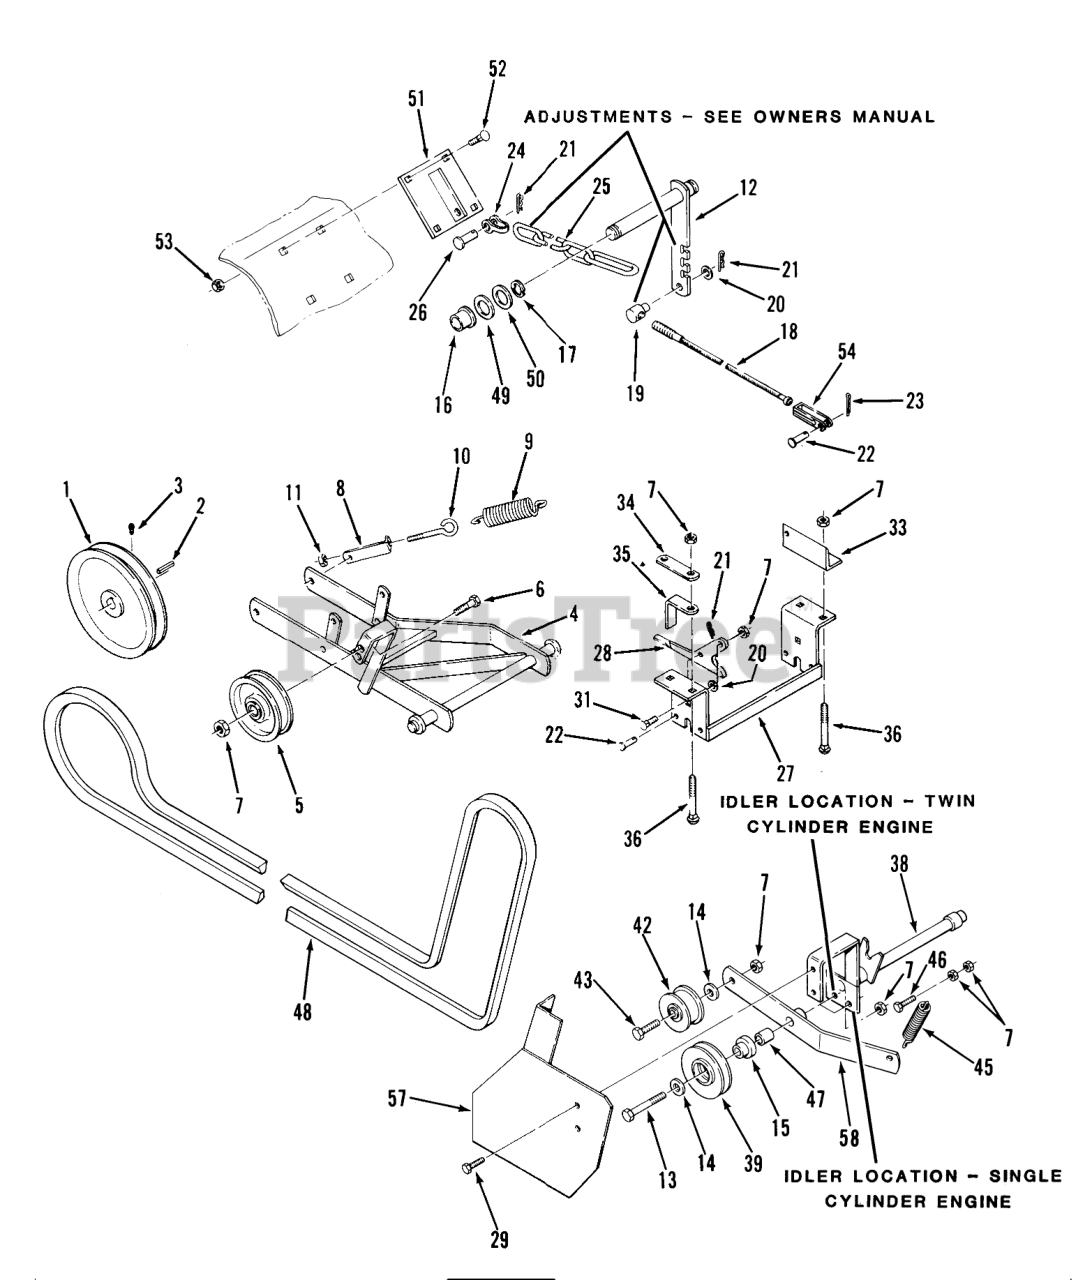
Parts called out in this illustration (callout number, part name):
1	Pulley
2	KEY-STRAIGHT
3	Set Screw
4	Hitch
5	Flat Idler
6	Bolt
7	Nut
8	Bracket-Spring
9	SPRING
10	EYEBOLT
11	NUT
12	ASSY LEVER R
13	Bolt
14	Washer
15	Spacer
16	BUSHING-BRONZE
17	E-RING
18	CABLE
19	TRUNNION-CLUTCH ROD
20	Washer
21	Hairpin
22	Pin
23	Cotter Pin
24	Clevis
25	CHAIN LIFT
26	Clevis Pin
27	Bracket
28	PLATE-LATCHING
29	Bolt
31	Bolt
33	LINK-BRACKET R
34	BRACKET-REAR LINK MOUNTING
35	SPACER-BRACKET
36	Bolt-Carriage
38	ASSY SUPPORT R
39	Pulley-V
42	IDLER PULLEY
43	BOLT
45	SPRING-BRAKE
46	Bolt
47	SPACER
48	V-BELT
49	WASHER
50	WASHER-SHIM
51	Lift Plate
52	Bolt
53	Nut
54	CLEVIS-SHORT
54	CLEVIS-LONG
57	ASM: FRONT IDLER R
58	Arm-Idler
